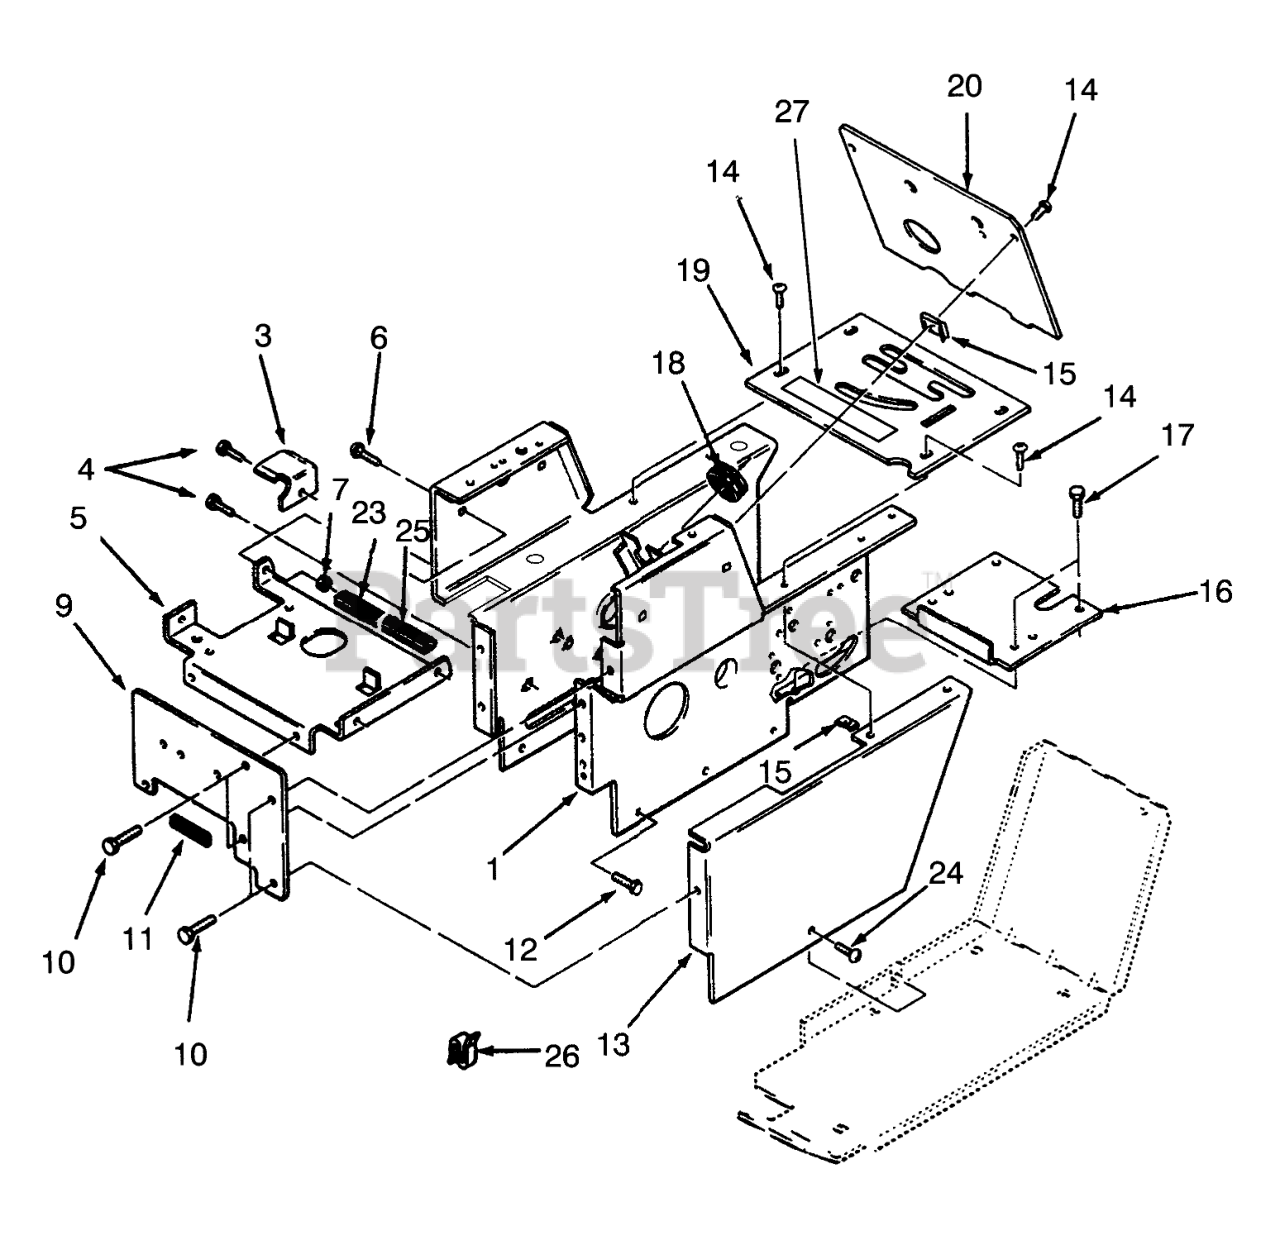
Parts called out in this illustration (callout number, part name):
1	Handstand
3	Bracket-Belt
4	Bolt
5	SUPORT-BATERYB
6	BOLT CARR. 5/16X1/2 BK
7	Nut
9	Front Plate
10	Bolt
11	EDGE TRIM 4IN OF 102896
12	Bolt
13	Cover-Side LH
14	SCREW-PPH
16	Cover-Dust
17	Bolt
18	GROMMET
19	Plate-Shift Cover (Incl. Ref. #27)
20	PLATE HOODSTAND B
23	EDGE TRIM 5" OF 102896
24	SCREW-PPH
25	EDGE TRIM 2" 102896
26	SPEED CLIP
27	DECAL-DANGER
